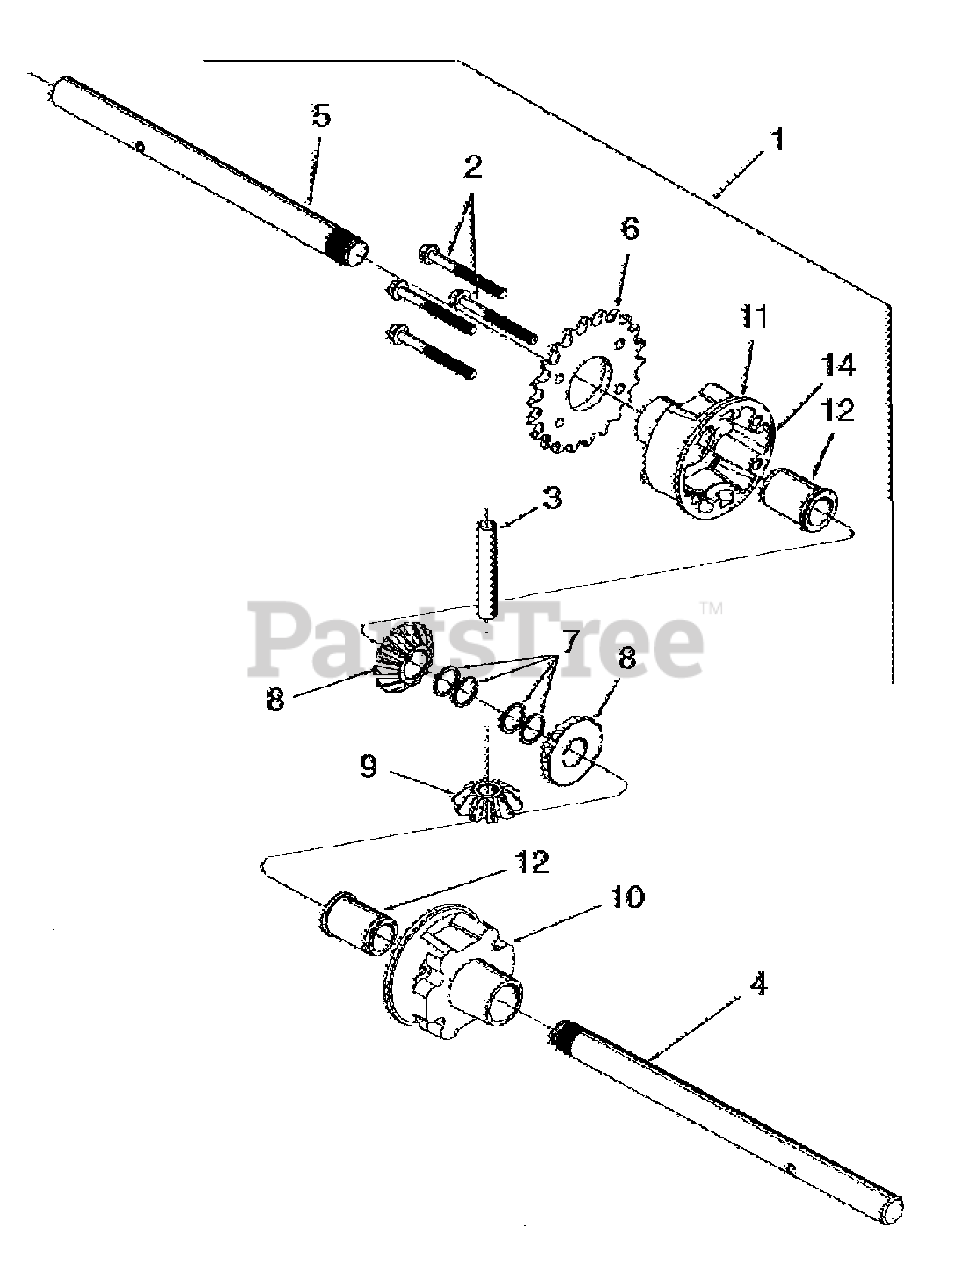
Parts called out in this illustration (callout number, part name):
1	Differential Ass'y Complete
2	Screw, Hex Wash Hd Tapp 1/4-20 x 2-5/16
3	Cross Shaft
4	Axle Shaft, .75 x 10.95
5	Axle Shaft, .75 x 9.82
6	Sprocket, 22T
7	Ring, Retaining
8	Gear, Differential, 14T
9	Gear, Differential, 10T
10	Housing, Differential RH
11	Housing, Differential LH
12	Bearing, Flange, .75 ID x 1.0 OD
14	Sealant, Ultra Grey Loctite 5699
